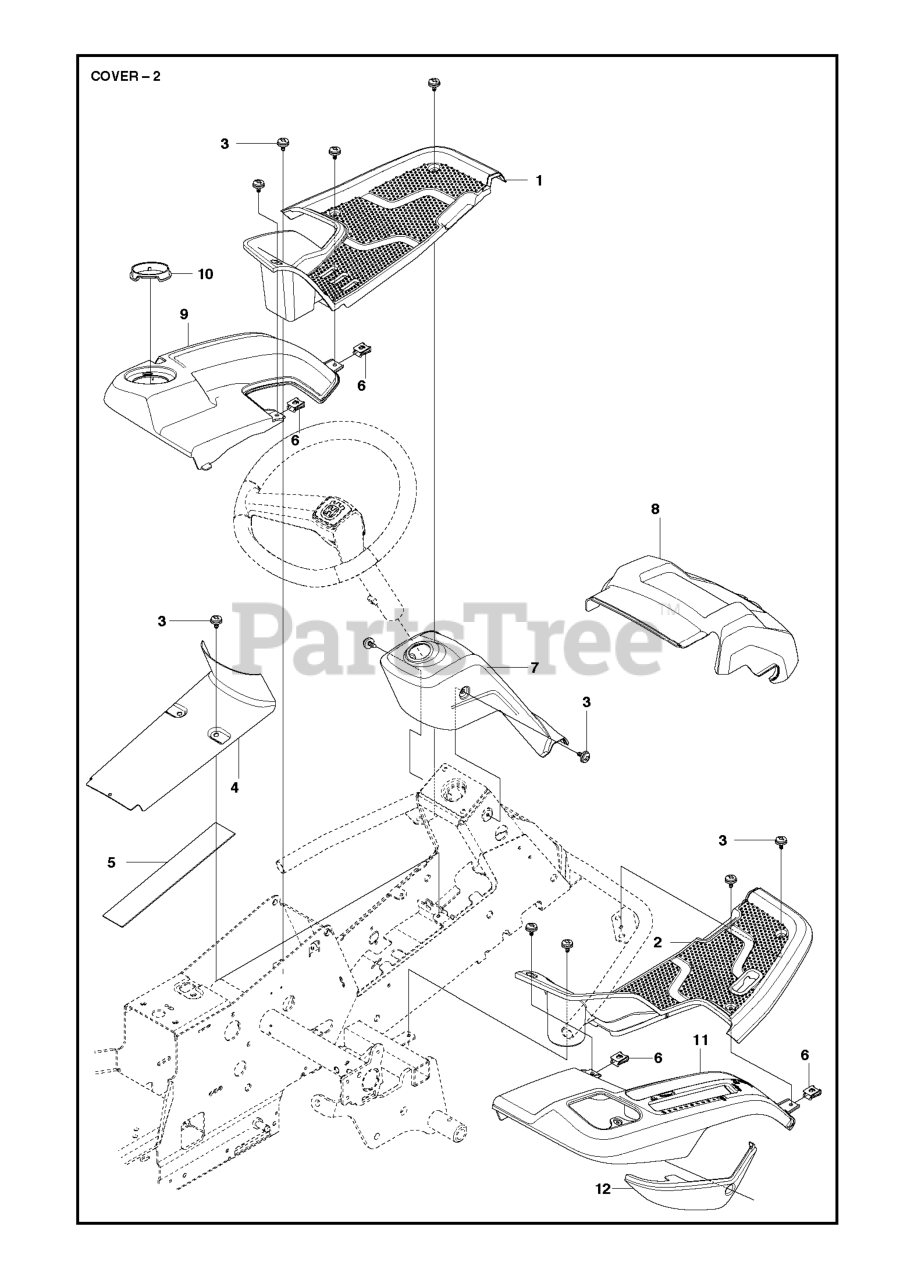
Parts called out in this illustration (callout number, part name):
1	FOOT PLATE
2	FOOT PLATE
5	MAT COVER FRAME
10	LOCKING NUT
12	CONTROL COVER
